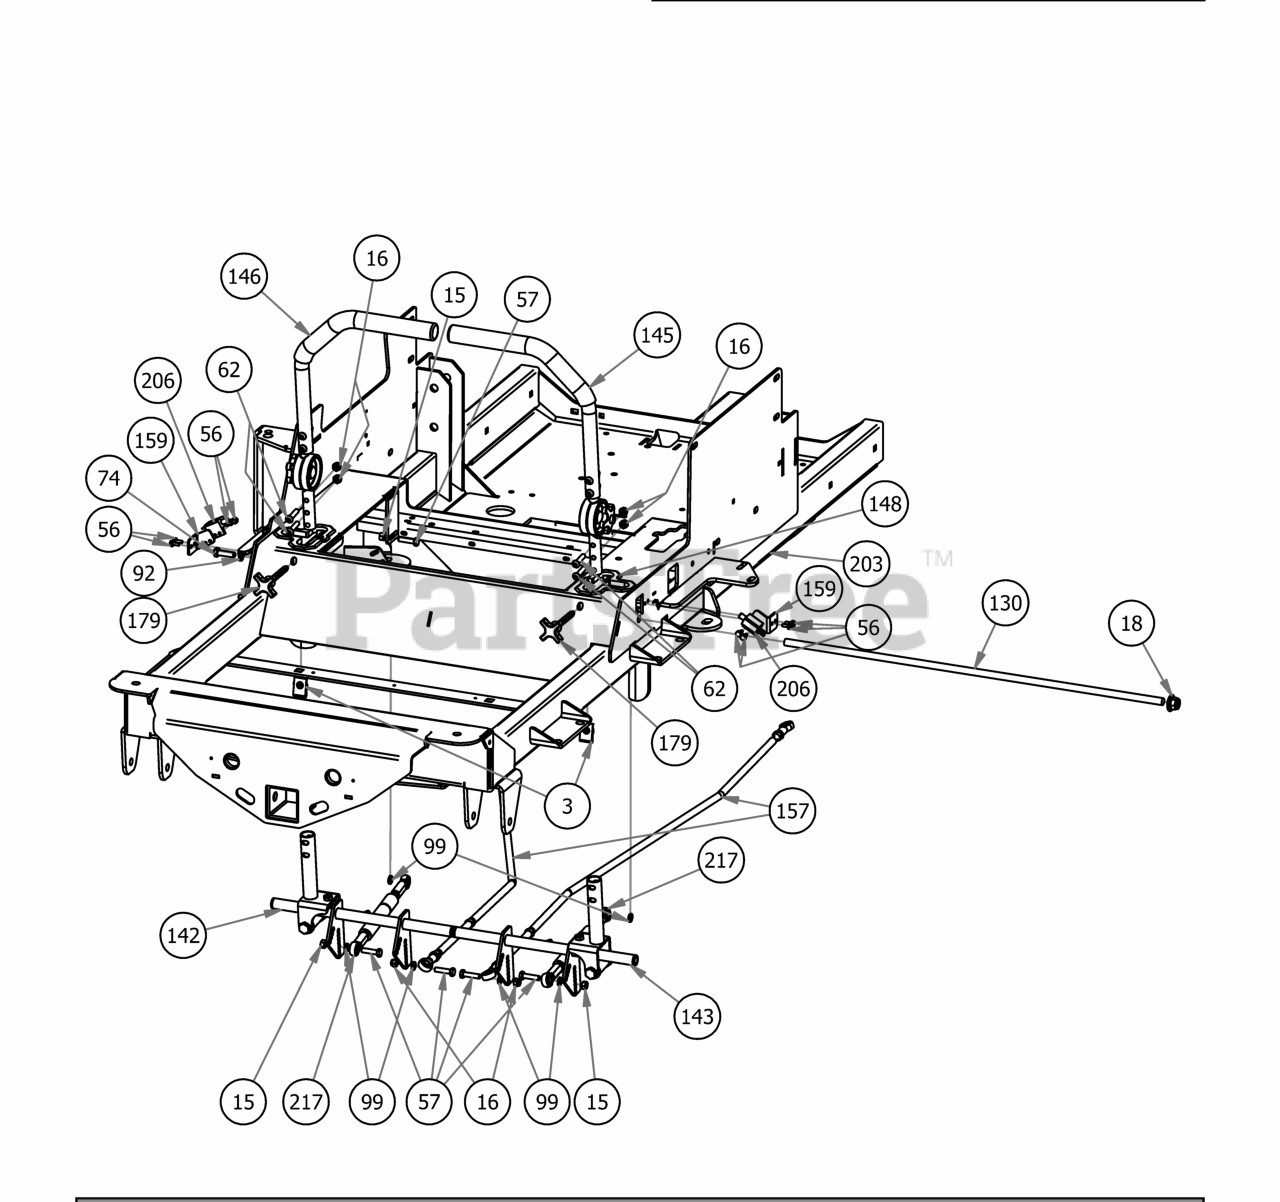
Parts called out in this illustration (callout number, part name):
3	Extruded Nut 3/8"-16 3/4" Hole Center With Patch
16	5/16-18 NYLON INSERT LOCKNUT ZINC ORANGE NYLON
18	1/2-13 NYLON INSERT FLANGE LOCKNUT ZINC
21	5/16" Flange Nut
56	12-24x 1/2 HWH Bolt
57	5/16 x 1 1/4 Hex Bolt
62	5/16-18 UNC X 1-3/8" BHCS, TORX DRIVE, GR 5
74	3/8" x 1 1/4" Hex Bolt
92	3/8" Lock Washer
99	5/16" Lock Washer
130	2019 Steering Actuator Rod
142	2019 R Series RH Arm Rod Assembly
143	2019 R Series LH Arm Rod Assembly
145	2019 Left Hand ADJ. Steering Arm Kit
146	2019 Right Hand ADJ. Steering Arm Kit
148	Snap-In Bushing-2019
157	2019 Outlaw Gen2 Horizontal Push Rod Assembly
159	2019 Arm Switch Bracket
179	Speed Limiting Knob 3/8-16X 3"
203	2019 Horizontal Gas Frame
206	Safety Switch
217	2019 SROID Damper With Spherical Rod Ends
